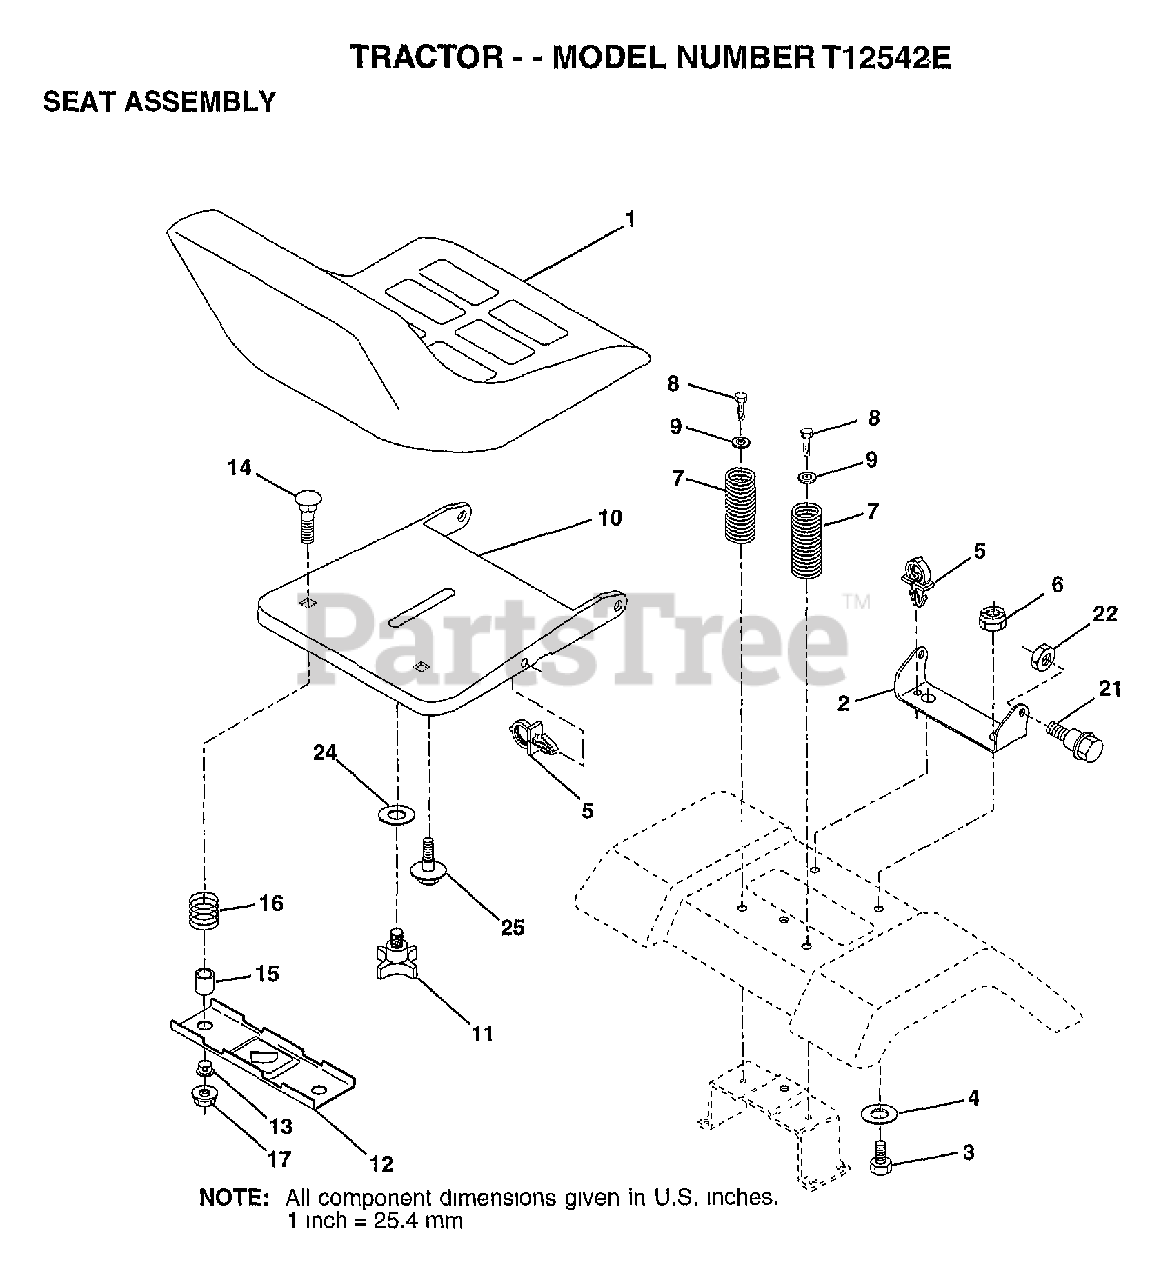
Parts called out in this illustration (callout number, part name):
2	BRACKET PVT SEAT
3	BOLT
4	WASHER PM
5	CLIP.PUSH-IN.HING
6	NUT
7	SPRING COMPRESSIO
8	SCREW GTV
9	WASHER
10	PAN-SEAT
11	"KNOB 1/2"" YT"
12	BRKT SWITCH
13	BUSHING
15	SPACER SPLIT
16	SPRING COMPRESSED
21	"BOLT,SHOULDER"
22	NUT
24	WASHER
25	"BOLT,SHOULDER"
